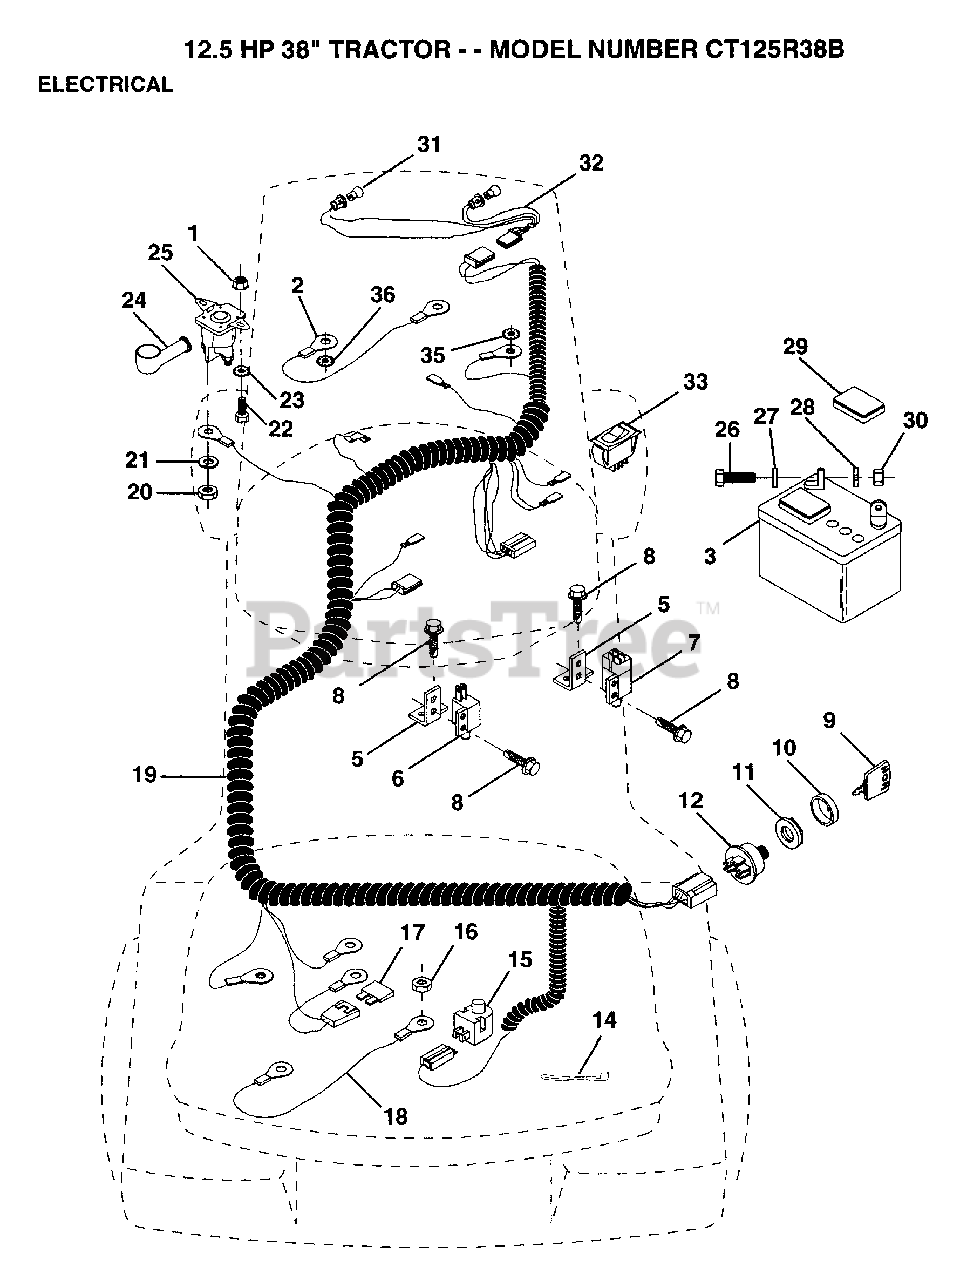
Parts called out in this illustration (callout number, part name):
1	NUT
2	CABLE ASM.
5	BRACKET LT
6	SWITCH-INTER. GT
7	SWITCH INTERLOCKT
8	SCREW
9	KEY
11	NUT IGNITION
14	WIRE TIE
15	SWITCH SEAT
17	FUSE HYT
18	CABLE ASSY
20	NUT
22	BOLT
26	BOLT LT
27	WASHER
28	LOCKWASHER
29	"CAP,BATTERY "
33	SWITCH LT
35	LOCKWASHER
36	LOCKWASHER
